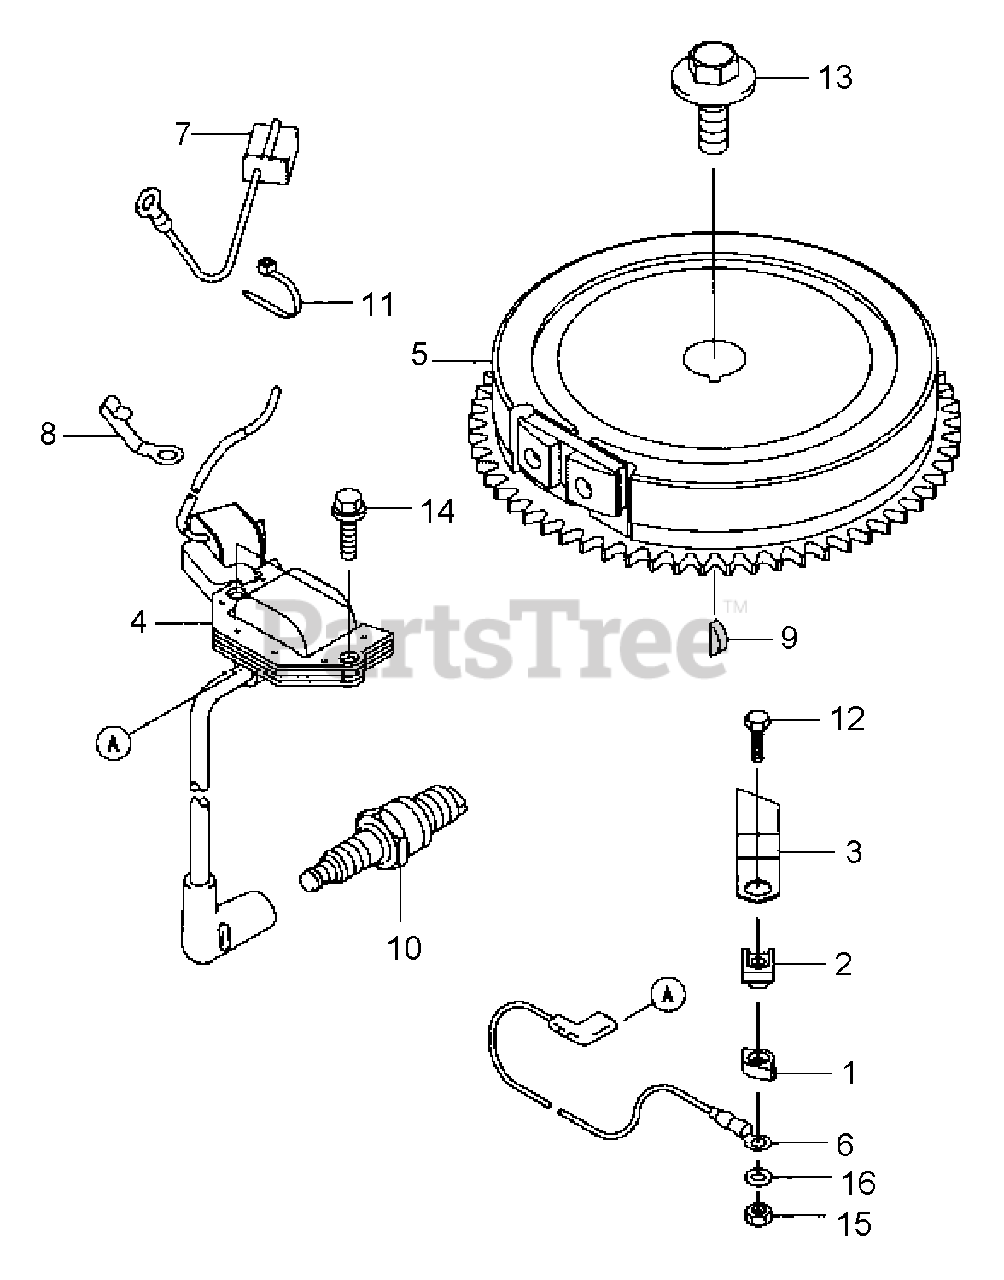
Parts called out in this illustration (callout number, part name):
4	Ignition Coil Assy.
10	Spark Plug
14	Flanged Bolt
15	Hex Nut
16	Plain Washer
